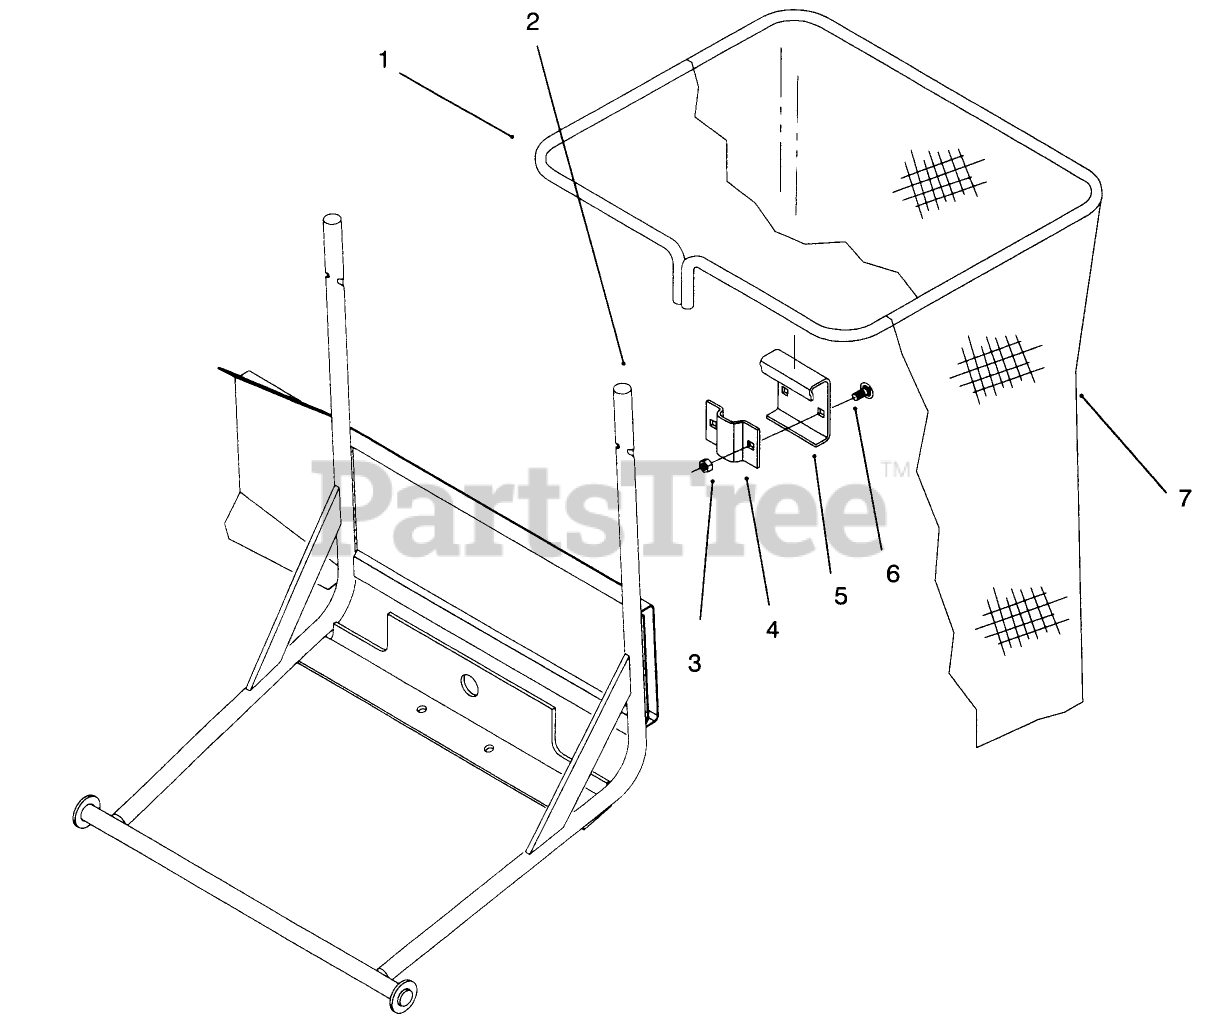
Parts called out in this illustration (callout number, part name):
1	Bag Frame
2	WLDMT-BAGGER RODS B
3	NUT-LOCK, NI
4	Clamp
5	Bag Hanger
6	BOLT-CARR
7	BAG-DEPTH
